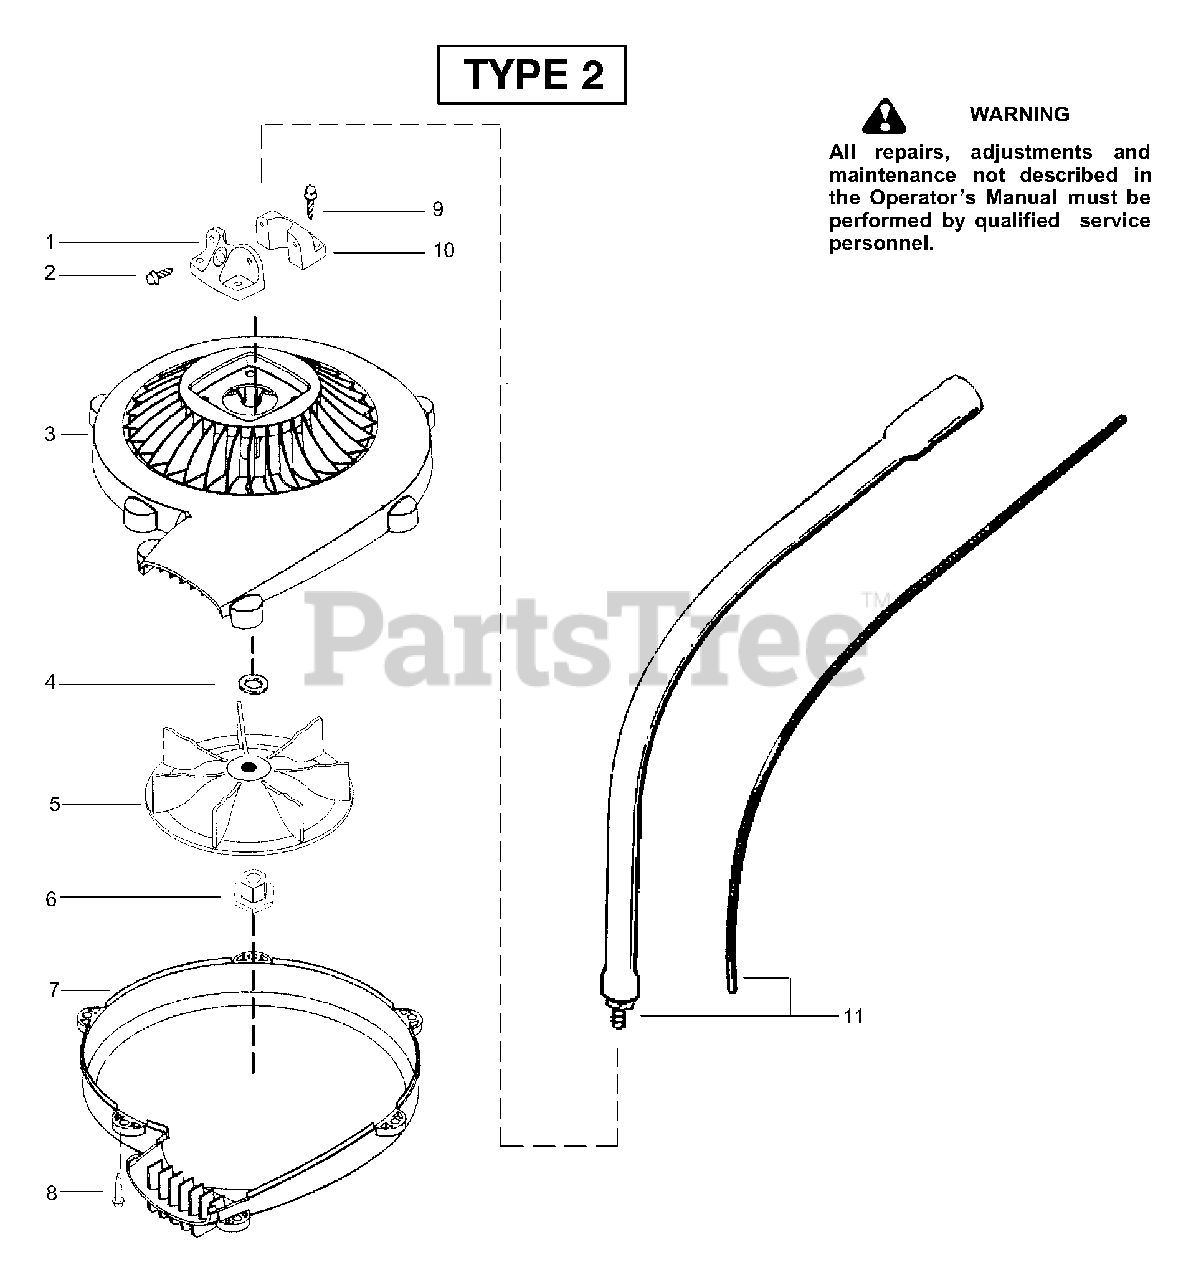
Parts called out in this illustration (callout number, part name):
1	Clamp-Right
3	Hsg.-Blower (upper)
5	Impeller
6	Arbor-Impeller
7	Hsg.-Blower (lower)
10	Clamp-Left
11	Assy-Lower Driveshaft
